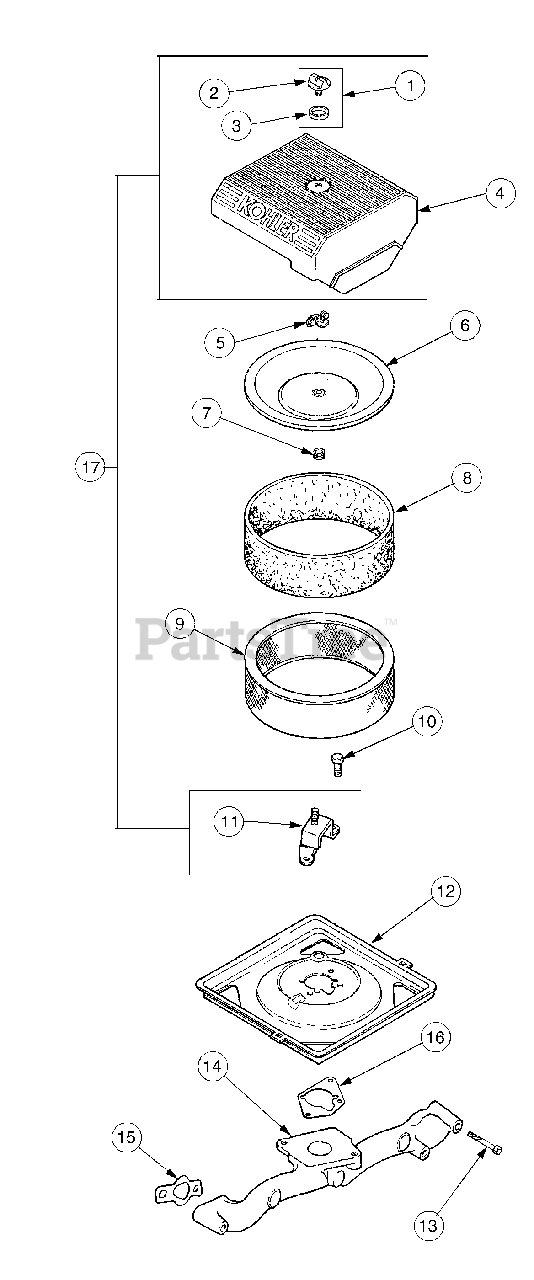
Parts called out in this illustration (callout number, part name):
1	Kit, Knob w/Seal
3	Seal, Air Cleaner Cover Knob
4	Cover, Air Cleaner
6	Cover, Inner Air Cleaner
7	Seal, Inner Air Cleaner
8	Precleaner, Element
9	Element, Air Cleaner
10	Screw, Hex Flange, M6 x 1.0 x 16
11	Bracket, Air Cleaner Base
12	Base, Air Cleaner
13	Screw, Hex Flange, M6 x 1.0 x 55
14	Manifold, Intake
15	Gasket, Intake Manifold
16	Gasket, Air Cleaner Base
17	Kit, Air Cleaner Cover
